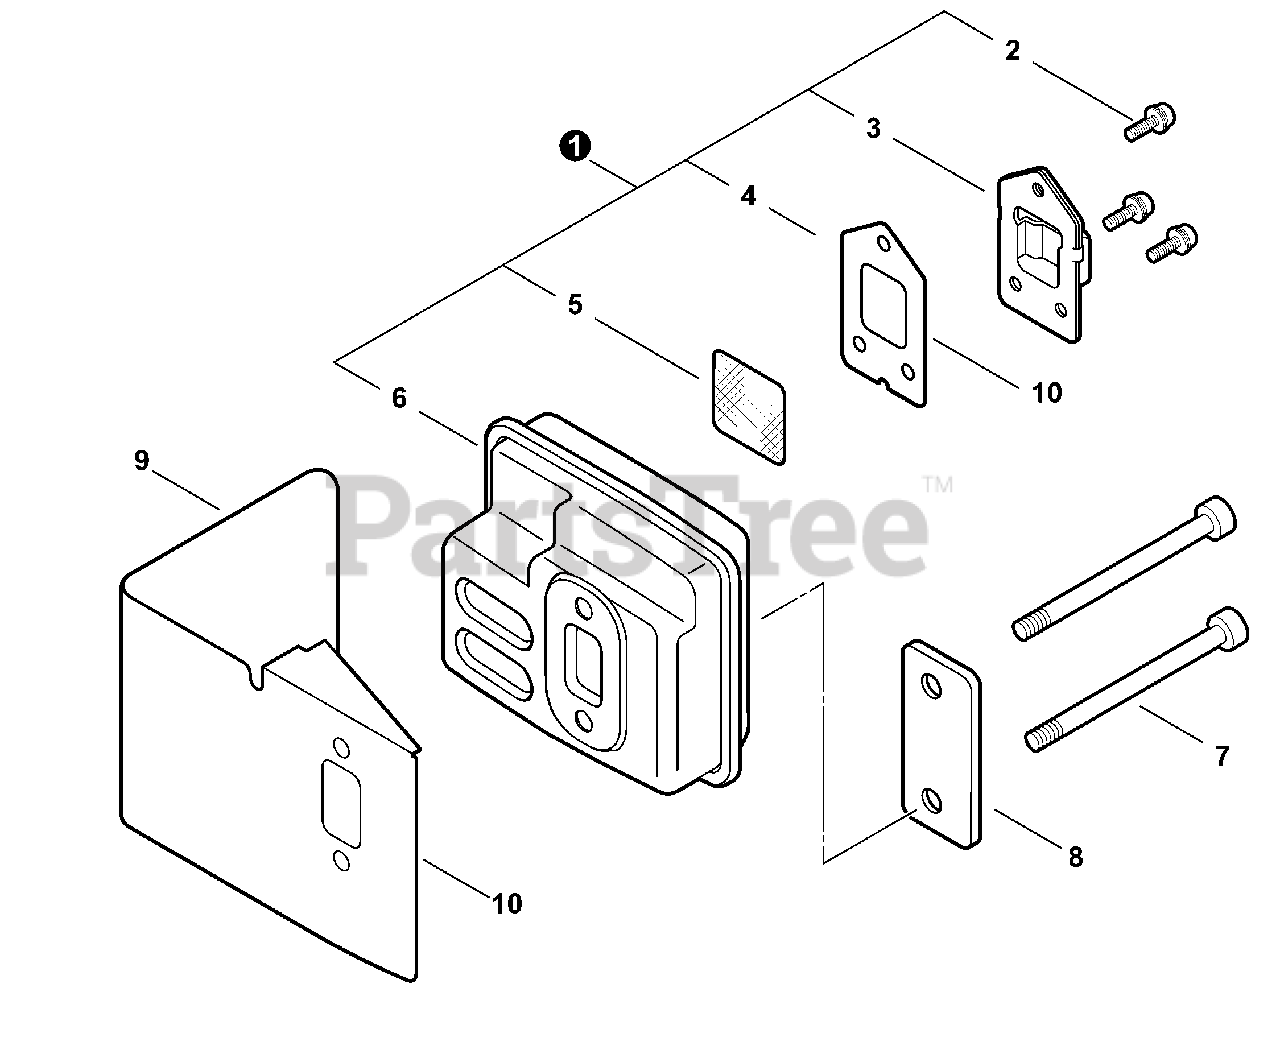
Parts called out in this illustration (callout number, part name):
1	MUFFLER ASSY
2	BOLT, TORX 4×8
3	GUIDE, EXHAUST
4	GASKET, EXHAUST
5	SCREEN, SPARK ARRESTER
7	BOLT, TORX 5×55
8	PLATE, EYE
9	HEAT SHIELD, EXHAUST
10	GASKET KIT
